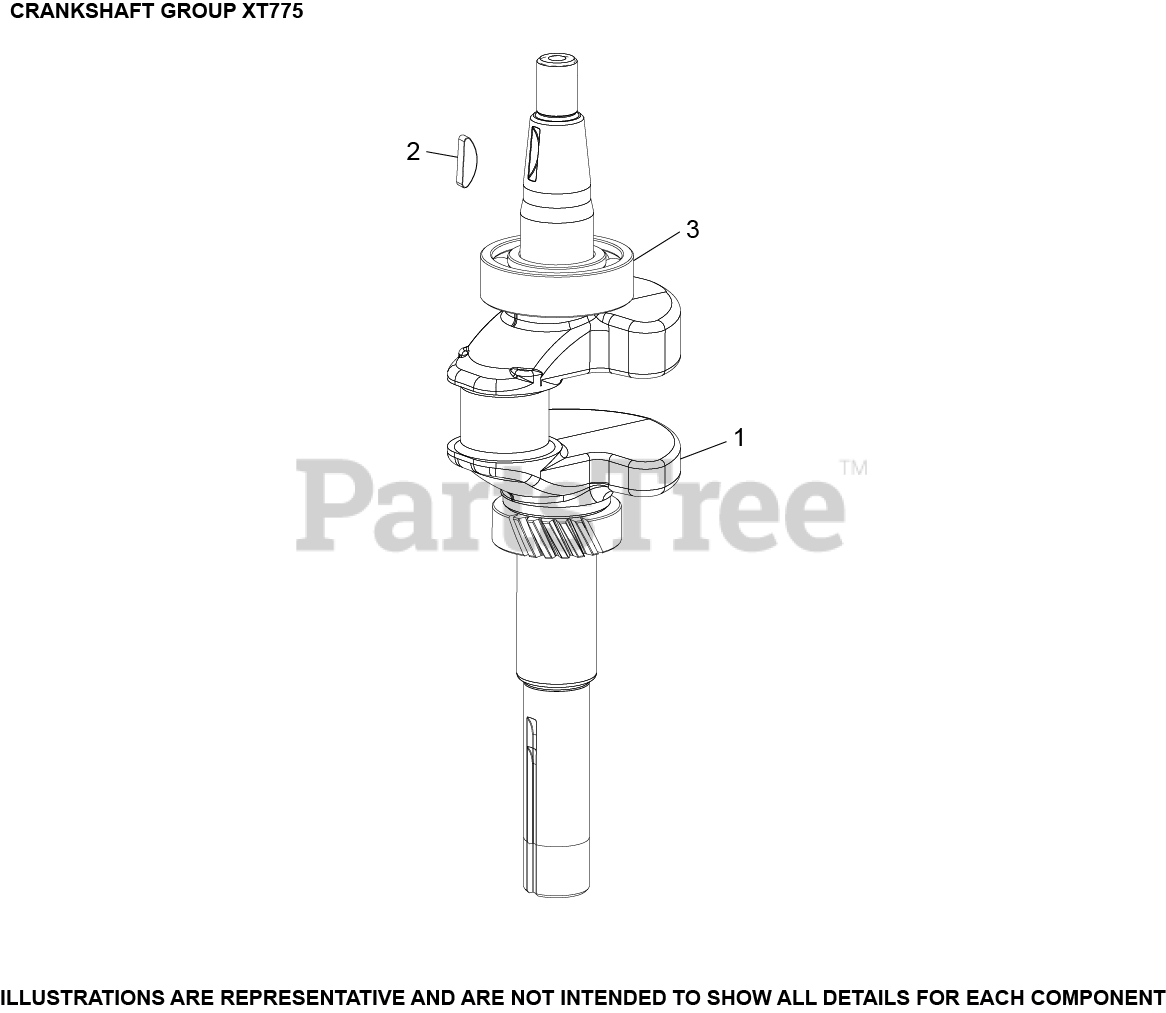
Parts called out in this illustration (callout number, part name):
1	CRANKSHAFT ASSEMBLY
2	KEY, FLYWHEEL
3	BEARING, BALL
